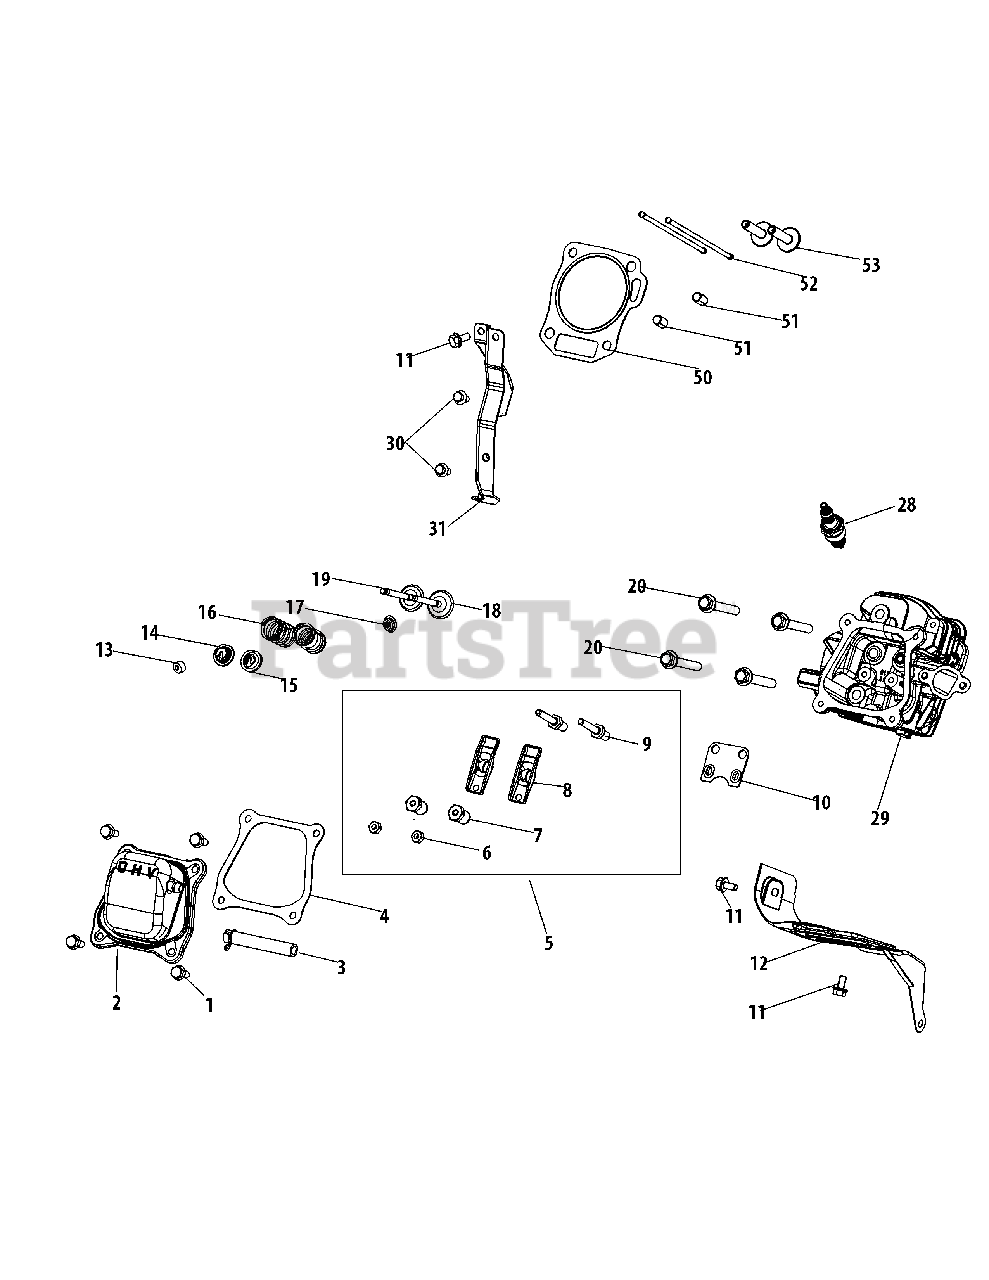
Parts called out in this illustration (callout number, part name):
1	Bolt, M6×16
2	Valve Cover
3	Breather Hose
4	Gasket, Valve Cover
5	Rocker Arm Assembly
6	Lock Nut
7	Adjust Nut
8	Rocker Arm
10	Rocker Arm Base
11	Bolt, M6×12
12	Shroud
13	Valve Adjust Cap, Exhaust
14	Valve Spring Seat
15	Valve Spring Seat
16	Valve Spring
17	Intake Valve Seal
18	Intake Vavle
19	Exhaust Valve
20	Bolt, M8×55
28	Spark Plug
29	Cylinder Head
30	Bolt, M6×12
31	Snow Guard
50	Gasket, Cylinder Head
51	Pin, 10×16
52	Push Rod
53	Tappet
